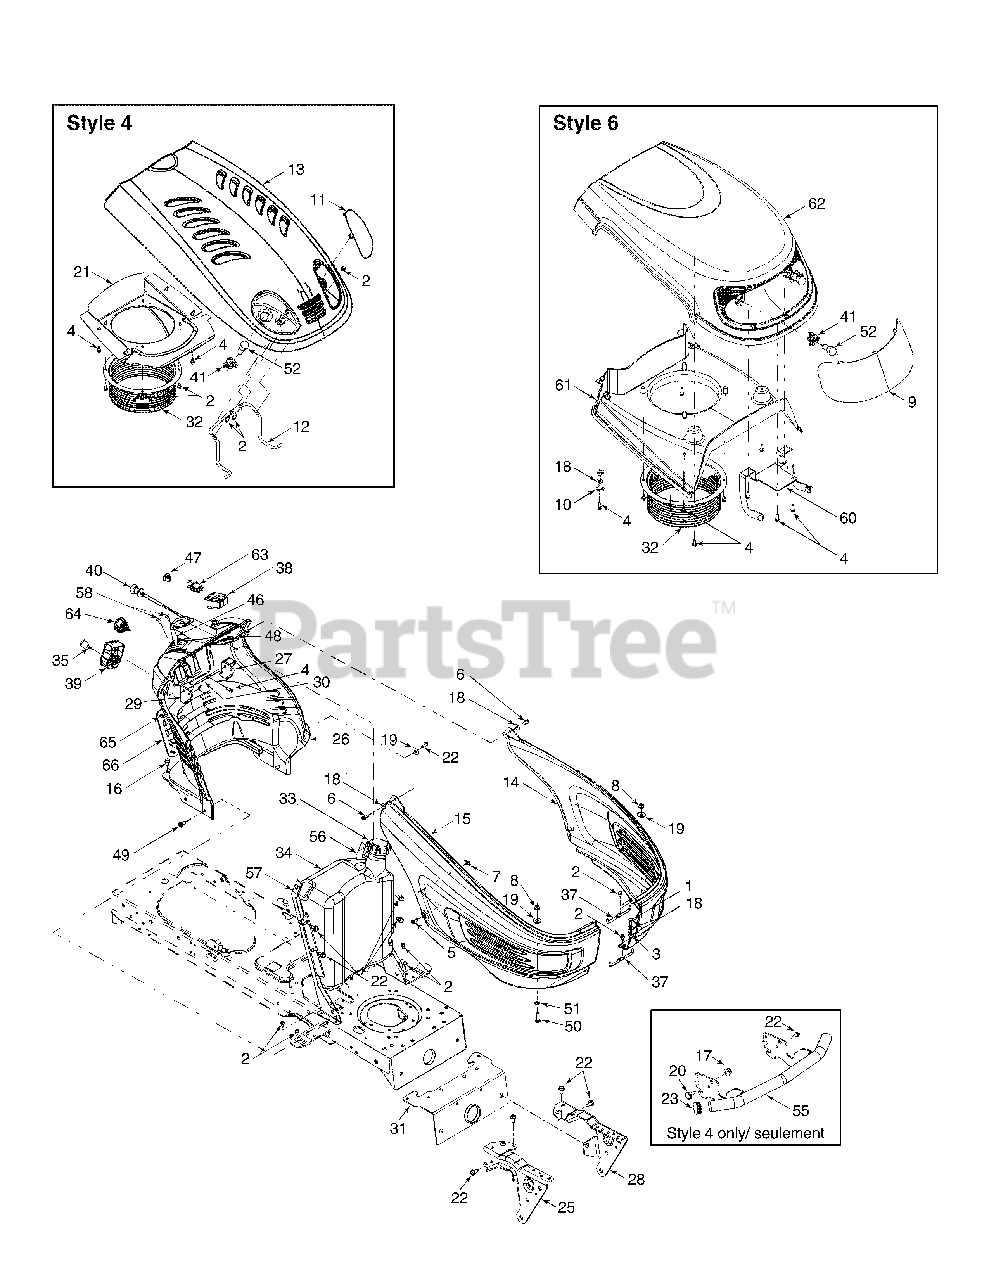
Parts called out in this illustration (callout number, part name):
1	Hex Cap Bolt 1/4-20 x .75" Lg. Gr. 5
2	Hex Wash S-Tapp Scr. 1/4-20 x .50
3	Hex L-Flanged Nut 1/4-20 Gr. F, Nylon
4	Hex Tapp Scr 1/4 x .75" Lg.
5	Truss Mach Scr 1/4-20 x .75" Lg.
6	Thd Forming Scr. 1/4-20 x .75 Lg.
8	Flange Locknut 5/16-18 Gr. F, Nylon
9	Head Light Lens Style 6
10	Hood Latch Rod
11	LH Head Light Lens Style 4
11	RH Head Light Lens Style 4
12	Hood Support Rod
13	Hood, Style 4 (Yellow)
14	LH Side Panel, Style 4, Yellow
14	LH Side Panel, Style 6
15	RH Side Panel, Style 4, Yellow
15	RH Side Panel, Style 6
16	Hex Wash HD AB Tap Scr 5/16-18 x .5
17	Flange Locknut 3/8-16 Gr. F, Nylon
18	Flat Washer .28 ID x .74 DE x .063
19	Flat Washer .344 ID x 1.0
20	Shoulder Scr. .498 x .340: 3/8-16
22	S-Tapp Scr 5/16-18 x .75
26	Dash Panel,
27	Parking Brake Button
30	Brake/Cruise Pivot Rod
32	Intake Bellow
33	Cap-Fuel
34	Fuel Tank 2 Gal.
34	Fuel Tank 3 Gal.
35	Ignition Key w/Plastic Cover
35	Ignition Key w/o Plastic Cover
37	Side Panel Support
38	Systems Indicator Monitor w/Hour Meter
38	Sys. Ind. Mon. w/Hr. Mtr., Curved Face
39	Ignition Switch-Export Module
40	Choke Cable 39" Lg.
40	Choke Cable 23" Lg.
41	Socket
46	Throttle/Choke Cable
48	Bracket - PTO Switch
49	Screw 5/16-18 x .75
50	Hex Scr 5/16 x 1,00 Gr. 5
51	Push Speed Nut
52	Miniature Lamp 12V Socket Type
53	Clevis Pin
54	Hairpin Cotter
61	Hood Plenum-Black
62	Hood, Style 6
62	Hood, Style 6, Beige
63	Electric PTO Switch
64	Ignition Switch
65	Ratchet Clip .30 Dia.
66	Accessory Net
67	Headlight Harness
